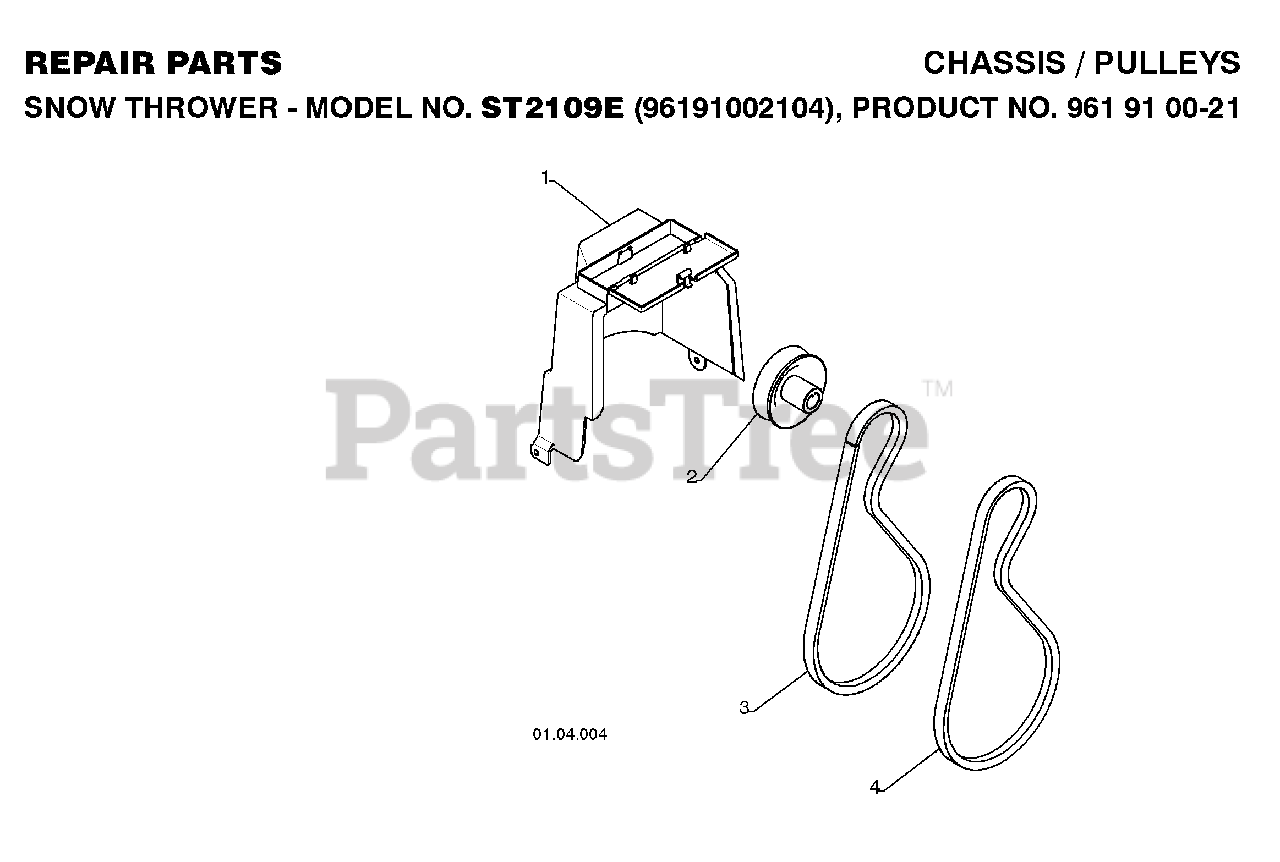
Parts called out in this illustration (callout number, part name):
1	COVER.BELT.HS
2	PULLEY
3	V-BELT.TRACTION
4	V-BELT, IMPELLER DRIVE
